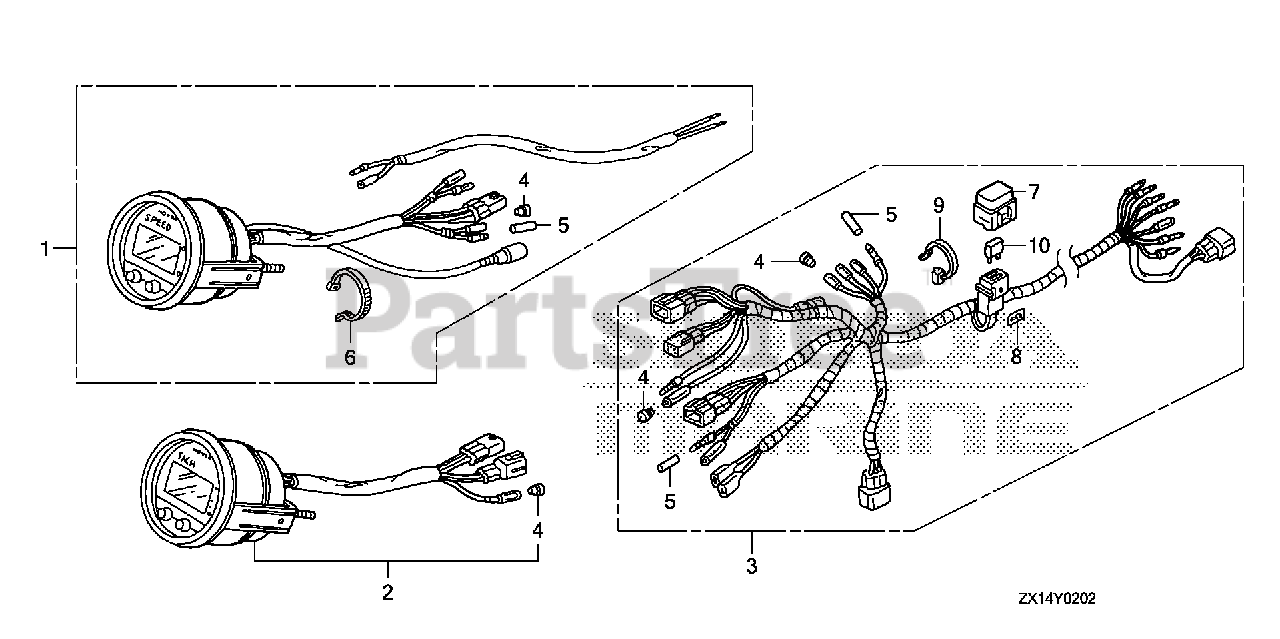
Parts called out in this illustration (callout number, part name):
1	SPEEDOMETER KIT (DIGITAL)(USA) (NOT AVAILABLE)
2	METER KIT, TACHO (DIGITAL)(USA) (NOT AVAILABLE)
2	METER KIT, TACHO (DIGITAL) (USE FOR 32540-ZY3-800/801)
3	HARNESS ASSY., METER (A)(DIGITAL)
4	PLUG, CONNECTOR (INNER)
5	PLUG, CONNECTOR (OUTER)
6	BAND (BLACK 3.5X140)
7	COVER ASSY., FUSE (7.5A)
8	MARK, FUSE (7.5A)
9	TIE, CABLE
10	FUSE, BLADE (7.5A)
